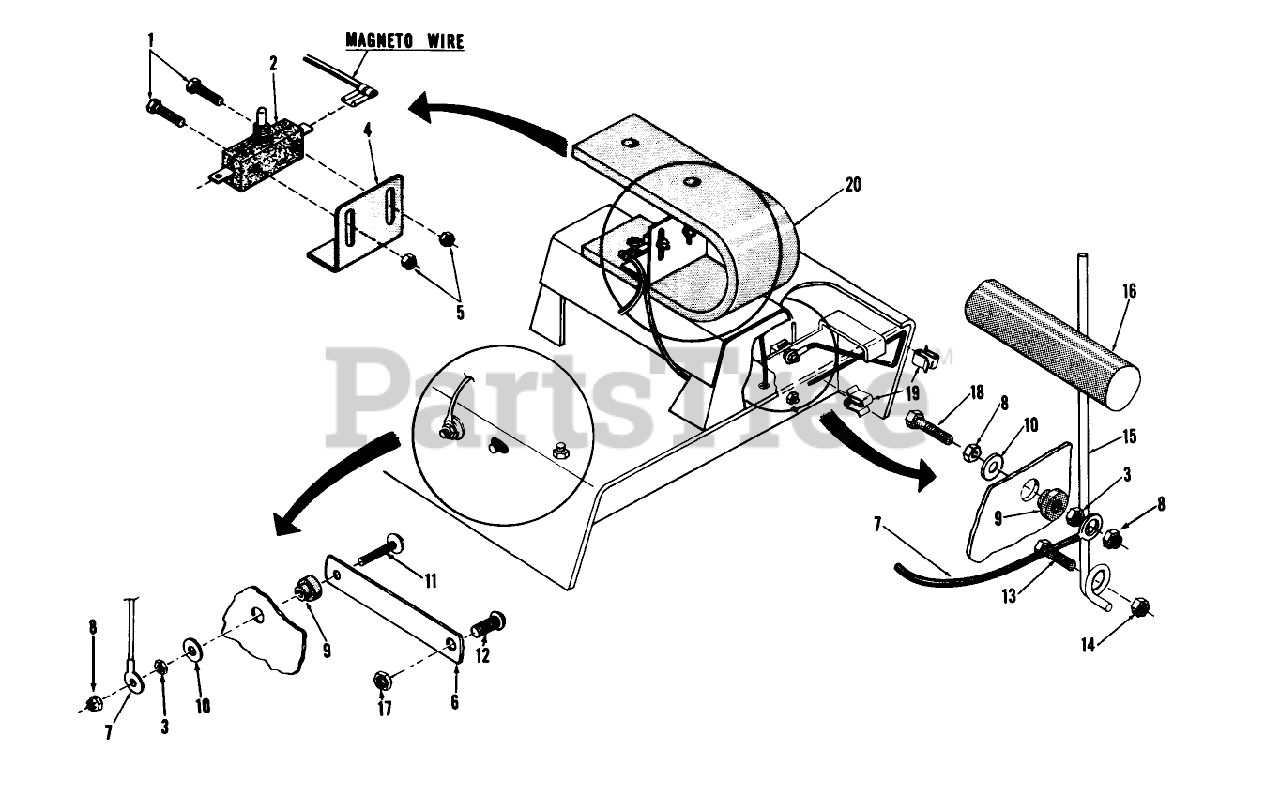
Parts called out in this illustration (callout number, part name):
1	DISC PREC HUSKY
2	Micro Switch
3	NUT, HEX
4	Bracket Switch
5	NUT, HEX
6	Spring
7	Wire Assy.
8	NUT-HEX
9	Washer
10	Washer
12	Screw
13	SCREW-HH
14	NUT-LOCK, NI
15	Spring
16	Lever
17	NUT-JAM
18	Screw
20	Seat Spring
